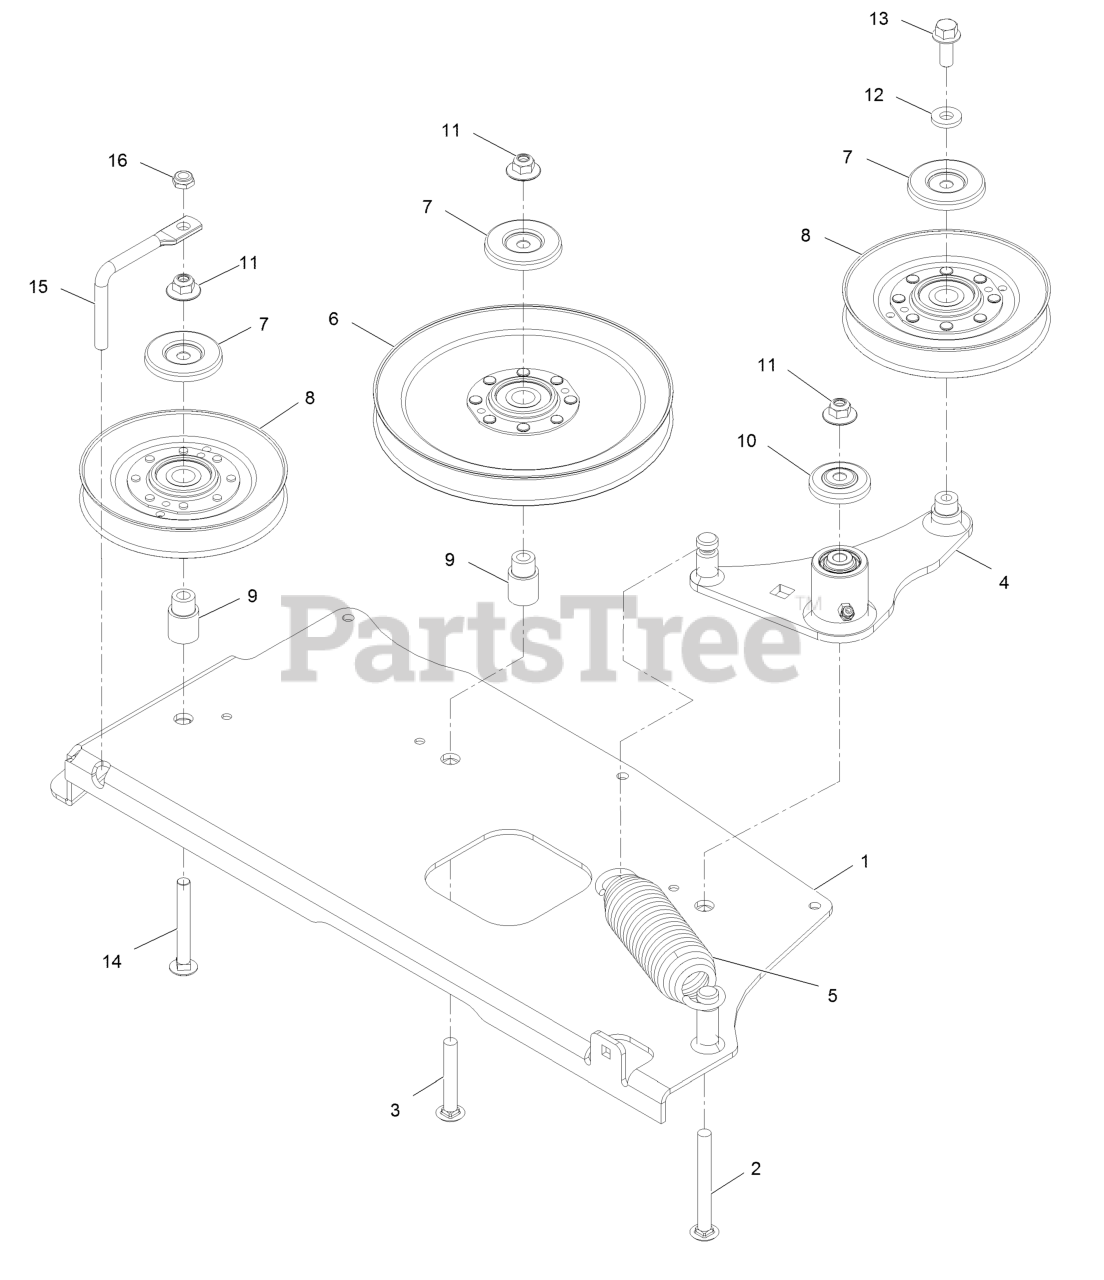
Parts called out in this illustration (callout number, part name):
1	Mount-Idler
2	Bolt-Carriage Shoulder 3/8-16 X 3 1/2
3	Bolt-Carriage 3/8-16 X 2 1/2
3	Ring-Retaining
4	Idler Arm ASM
4	Bearing-Spherical
5	Spring-Extension
6	Seal-Lip, Double
6	Idler-V
7	Seal-Single Lip
7	Shield-Dust
8	Idler V
9	Standoff-Idler
10	Guard-Top
11	Nut-Nyloc 3/8-16 Flg
13	Screw-HH Flg 3/8-16 X 1
14	Bolt-Carriage 3/8-16 X 3
15	Guide-Belt
16	Nut-Nyloc 3/8-16 Thin
